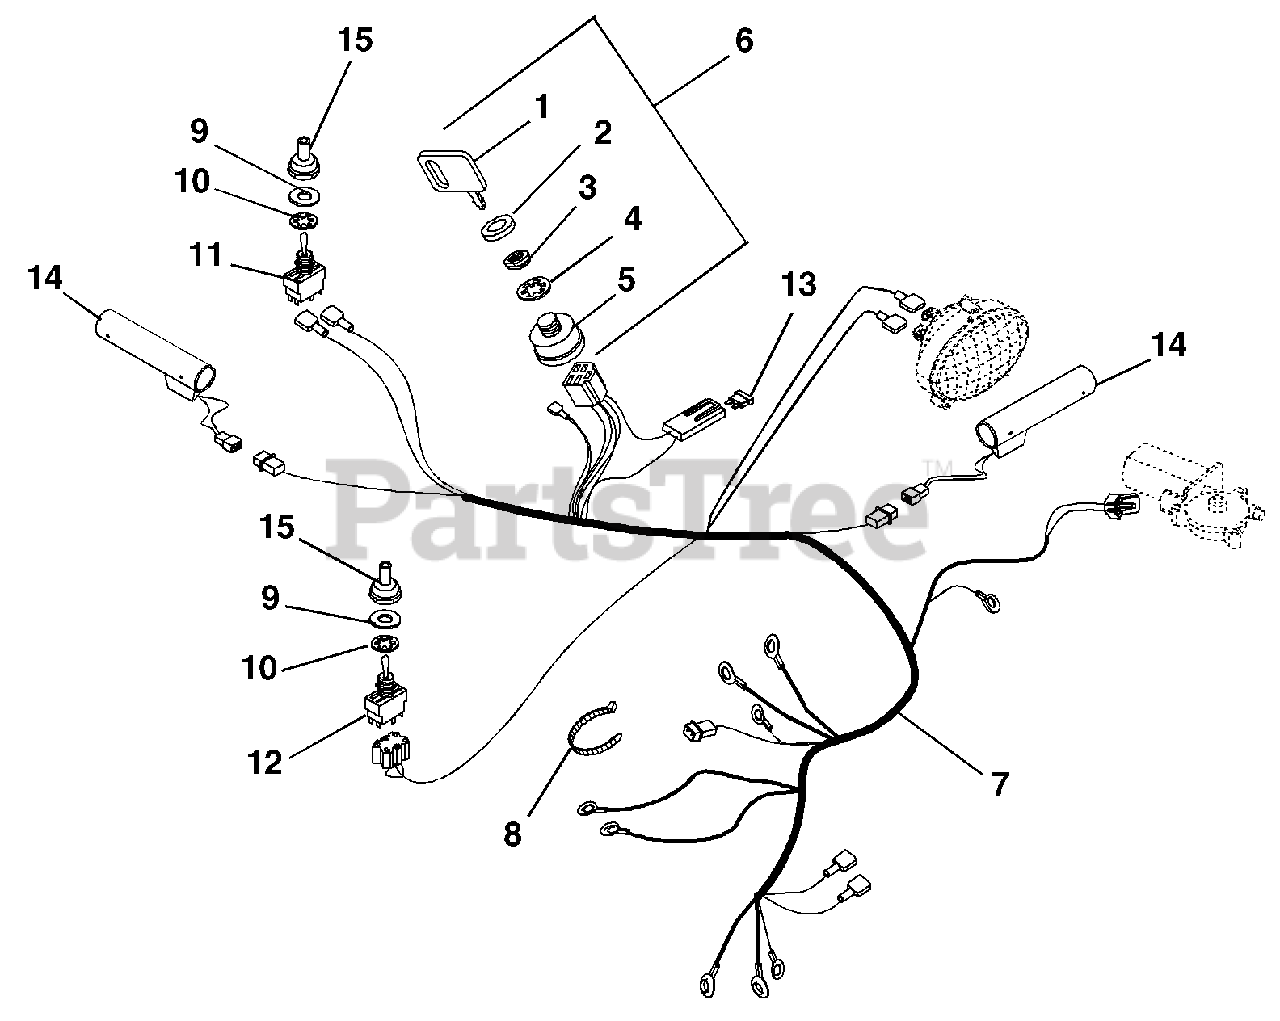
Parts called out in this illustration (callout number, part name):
1	KEY -W/CAP
2	CAP - IGNITION SWITCH
3	NUT-PANEL .625-32 GRECO
4	WSHR-LK-INT .625X.045 YWZC
5	IGNITION SWITCH ASSEMBLY
6	SWITCH ASSEMBLY
7	HARNESS, WIRING-LIGHT&HOT GRIP
7	HARNESS, WIRING-LT,HG,12V
7	HARNESS, WIRE-LT,HG,12V,CHUTE
8	CABLE TIE LG 5-1/2
9	WSHR-FL-STL .505X.875X.024 PL
10	WSHR-LK-INT .563X.040 YWZC
11	SWITCH, ON/OFF
12	SWITCH, CHUTE ROTATION
13	FUSE, 15 AMP.
14	WARMER, HAND W/TERMINAL
15	BOOT, SWITCH
